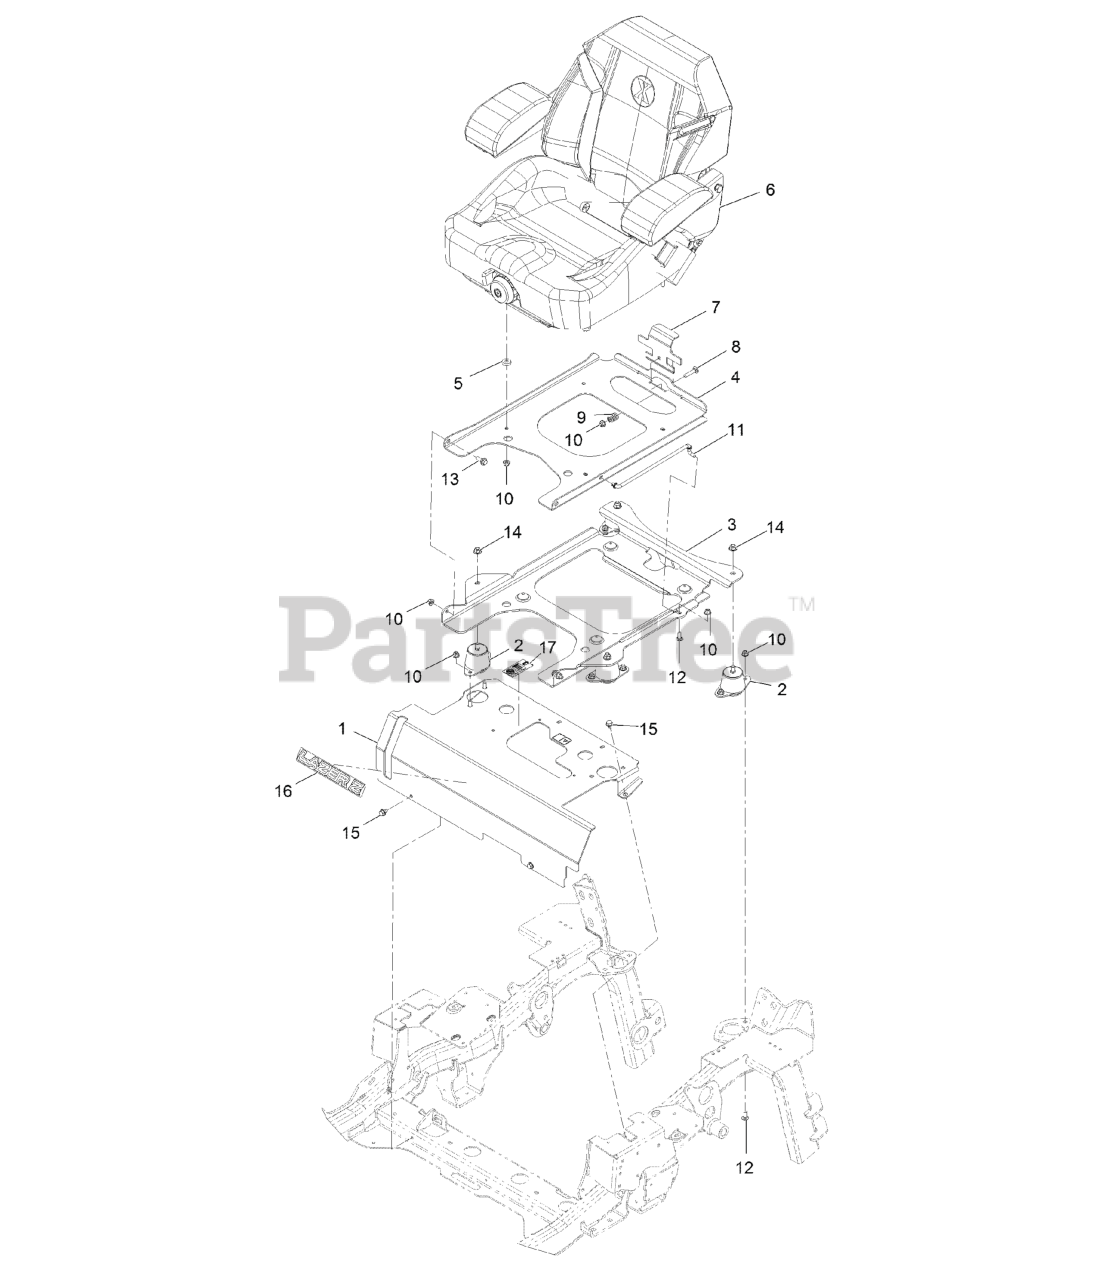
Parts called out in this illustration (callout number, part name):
1	SEAT MOUNT ASM
2	ISOLATOR-SEAT
3	PLATE-SUPPORT, TILT SEAT
4	PLATE-FRAME, SEAT
6	KIT-SUSPENSION SEAT
7	PLATE, SEAT LATCH
8	BOLT-CARR
9	SPRING-COMPRESSION
10	NUT-HF, NI
11	ROD-PROP
12	SCREW-CARR
13	SCREW-SHOULDER
14	NUT-HF, NI
16	DECAL, LAZER MODEL
17	DECAL-TRANS FLUID
